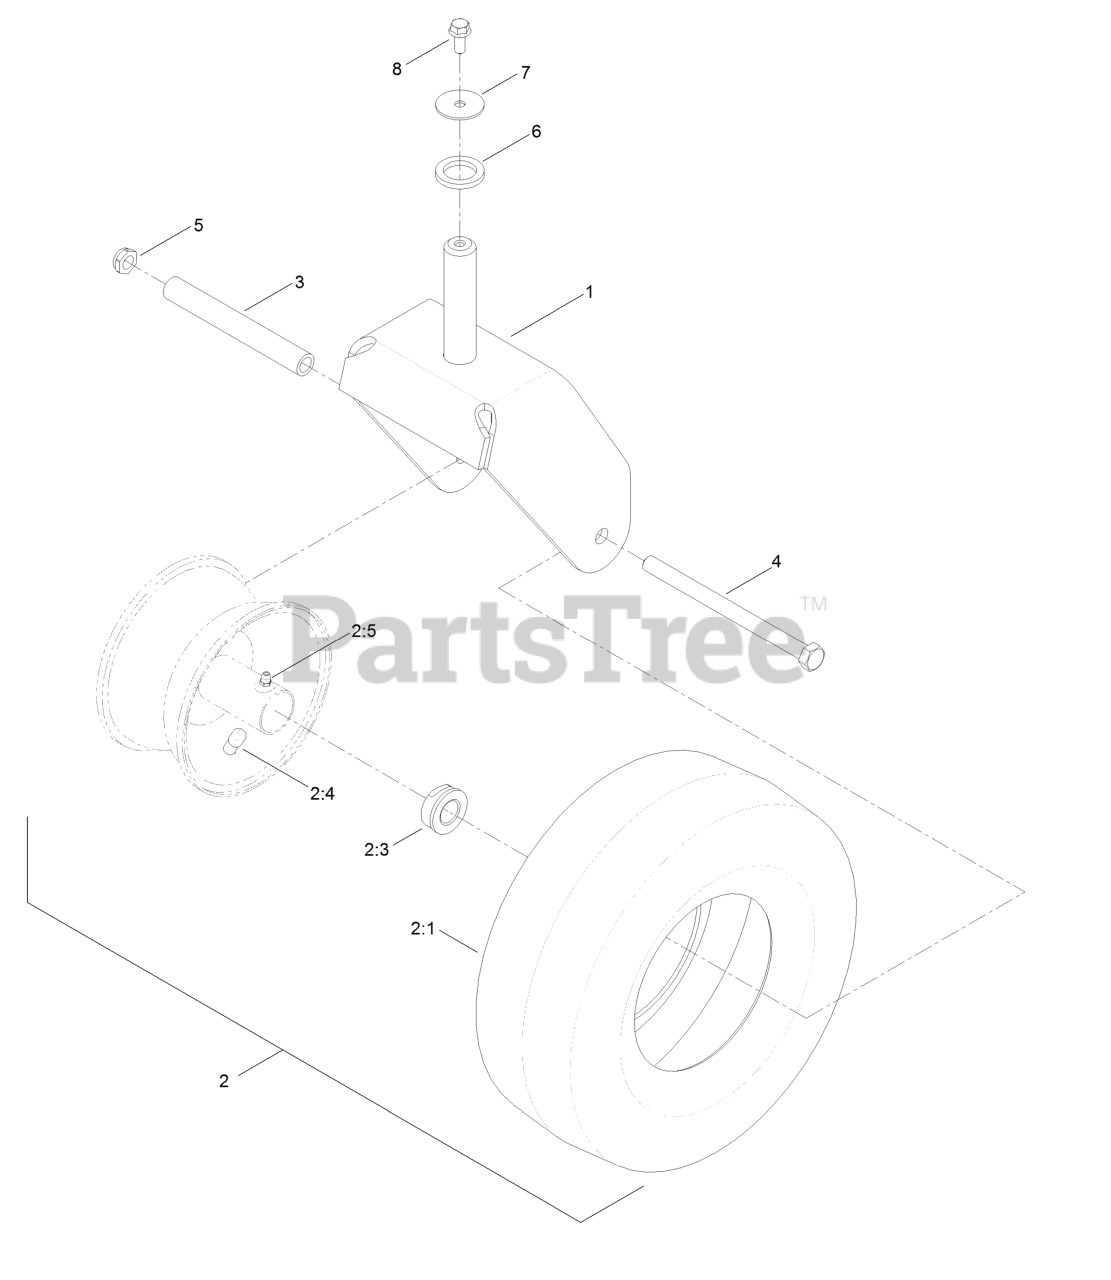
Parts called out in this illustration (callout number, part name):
1	FORK-CASTER
2	13 INCH WHEEL AND TIRE AS
2:1	TIRE-13 INCH
2:3	BUSHING-FLANGE
2:4	Stem-Valve
2:5	FITTING-GREASE
3	SPANNER
4	WASHER-LOCK
5	NUT-HEX
6	WASHER-THRUST
7	WASHER-FLAT
8	SCREW-HHF
